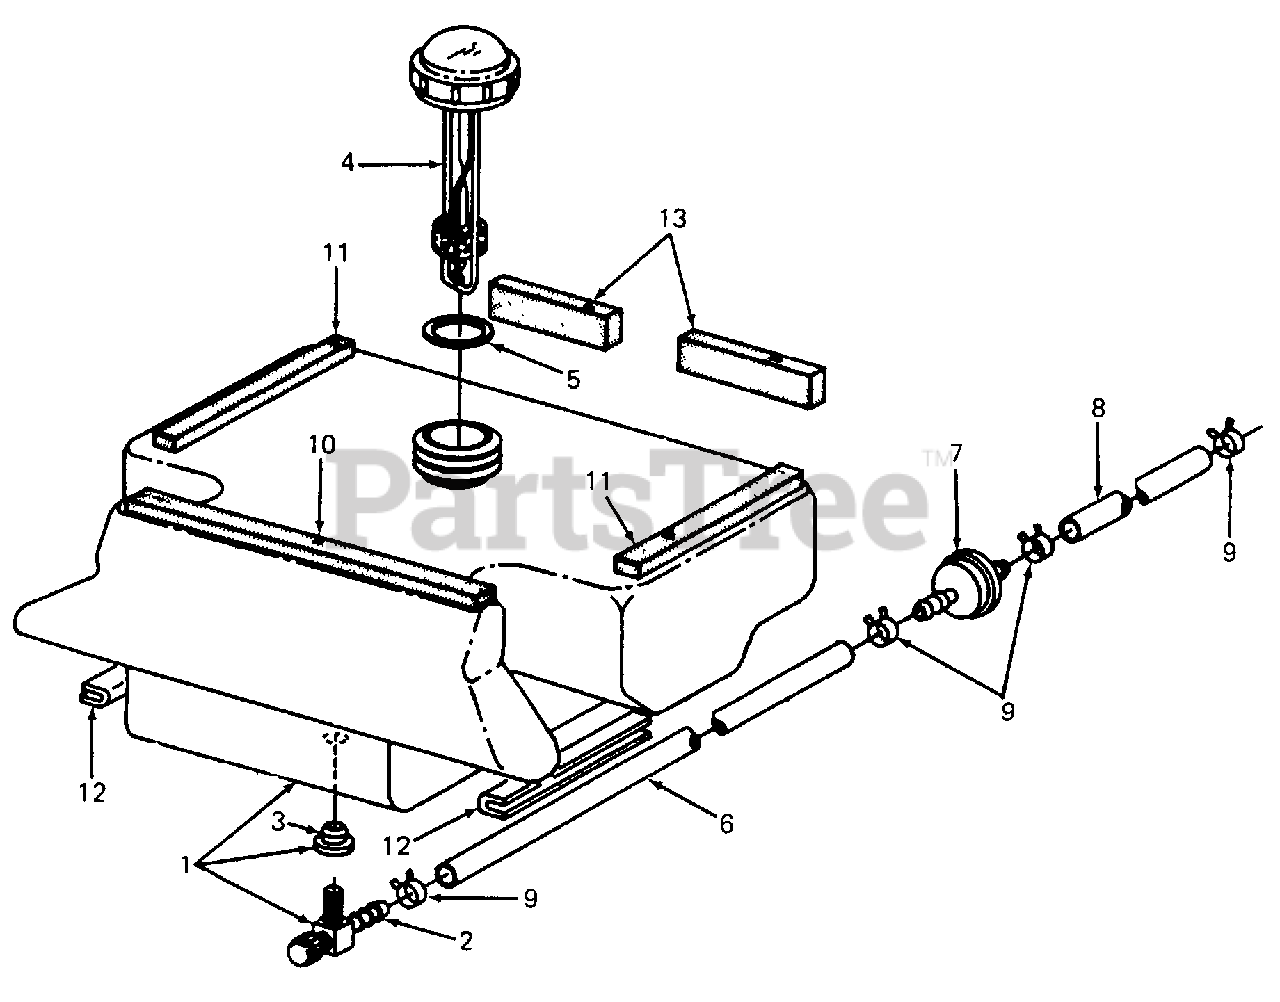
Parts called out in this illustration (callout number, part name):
1	Tank Assy, Fuel
2	Valve w/Screen, Shut-off
3	Bushing
4	Cap w/Gauge, Fuel Tank
5	Gasket, Fuel Tank Cap
6	Line, Fuel Tank To Filter, 56 in. Long
7	Filter, Fuel
8	Line, Fuel Filter To Engine, 25 in. Long
9	Clamp, 1/2 OD Tube Hose
10	Strip, Foam Gasket Sealing 12 in. Long
11	Strip, Foam Gasket Sealing 5 in. Long
12	Seal, Edge, 4 in. Long
13	Strip, Foam Gasket Sealing 3 in. Long
